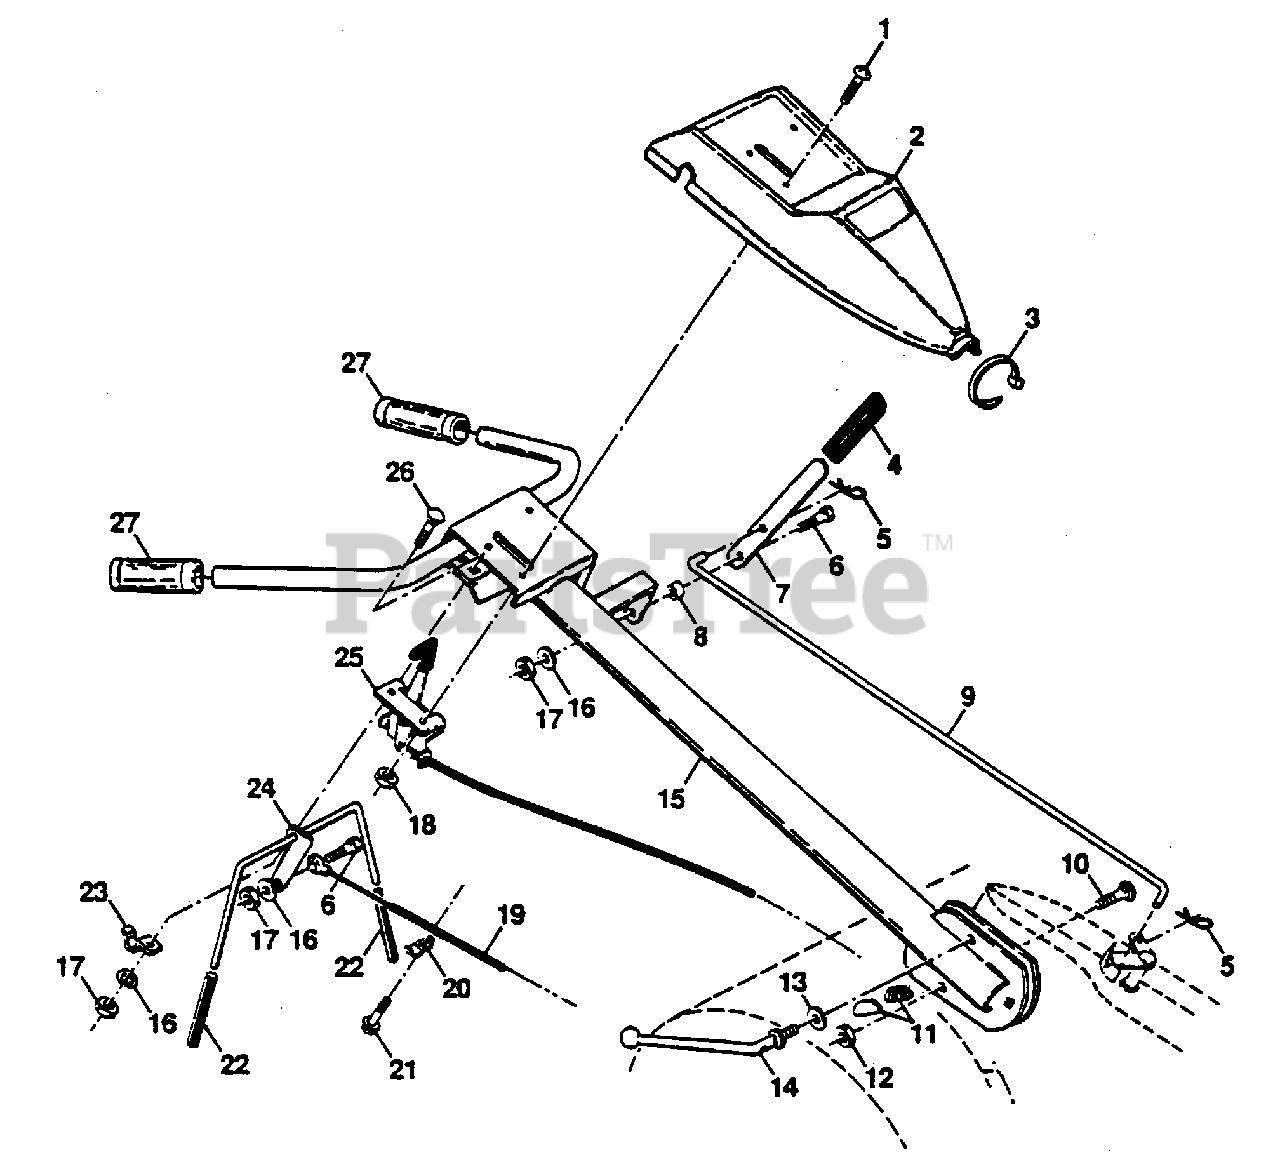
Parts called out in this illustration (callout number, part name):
1	Screw, Phd. #10-24 (AYP part number)
2	Panel, Control (AYP part number)
3	Tie, Cable (AYP part number)
4	Grip, Handle (AYP part number)
5	Clip, Hairpin (AYP part number)
6	Bolt, Shoulder (AYP part number)
7	Handle, Shift (AYP part number)
8	Grommet, Rubber (AYP part number)
9	Rod, Shift (AYP part number)
10	Bolt, Carriage 3/8-16 x 1 Gr. 5 (AYP part number)
11	Lock, Handle (AYP part number)
12	Nut, Centerlock 3/8-16 (AYP part number)
13	Washer 13/32 x 1 x 11 Ga. (AYP part number)
14	Lever, Lock, Handle (AYP part number)
15	Handle (AYP part number)
16	Washer, Lock 1/4 (AYP part number)
17	Nut, Hex 1/4-20 (AYP part number)
18	Nut, Keps #10-24 UNC (AYP part number)
19	Cable, Clutch (AYP part number)
20	Clip (AYP part number)
21	Screw, Hex Washer Hd. Slotted #10-24 x 1/2 (AYP part number)
22	Grip, Bar, Control (AYP part number)
23	Clamp, Bar, Control (AYP part number)
24	Bar Assembly, Control (AYP part number)
25	Control, Throttle (AYP part number)
26	Bolt, Carriage 1/4-20 UNC x 1/2 (AYP part number)
27	Grip, Handle (AYP part number)
